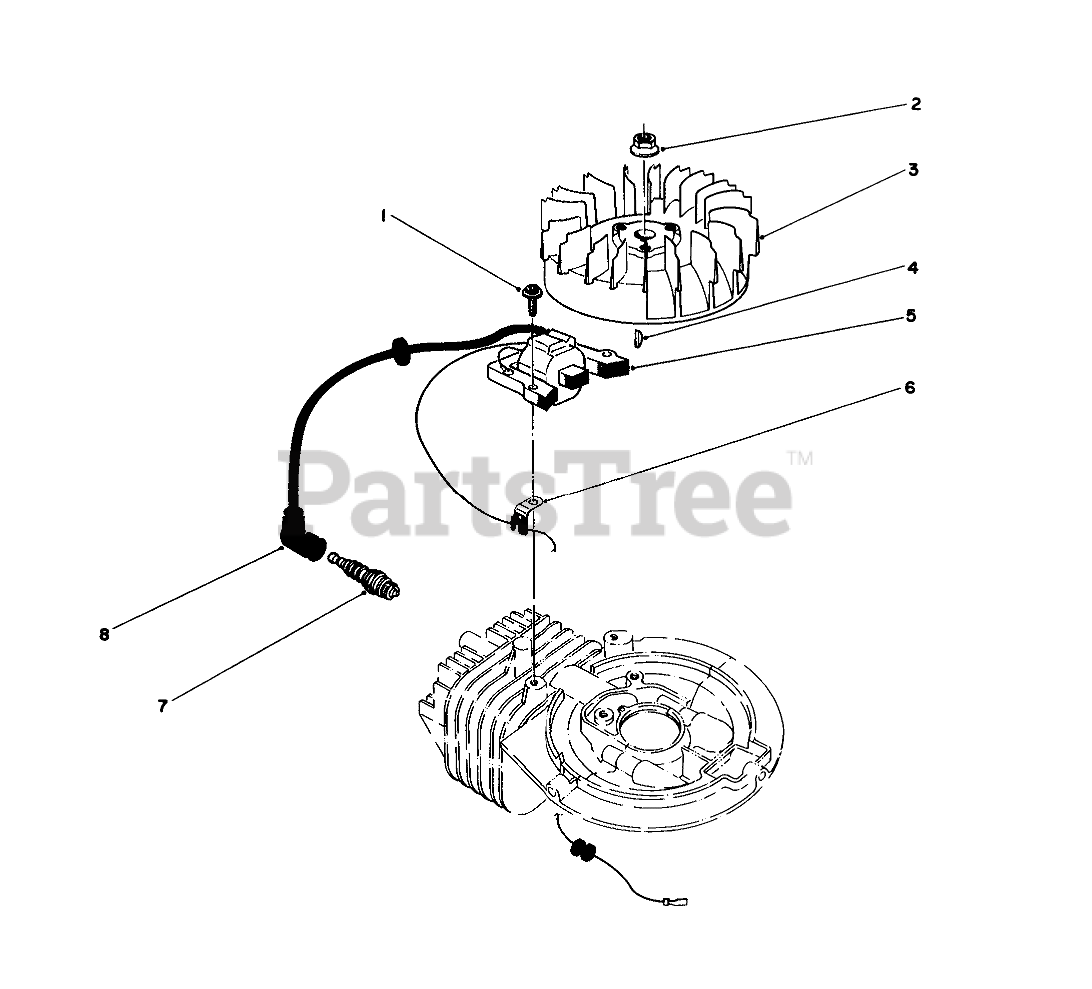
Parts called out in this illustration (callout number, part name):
1	Allenhead
3	FLYWHEEL
5	COIL-MAGNETO
6	CLAMP
7	Sparkplug
8	CAP-SPARKPLUG
